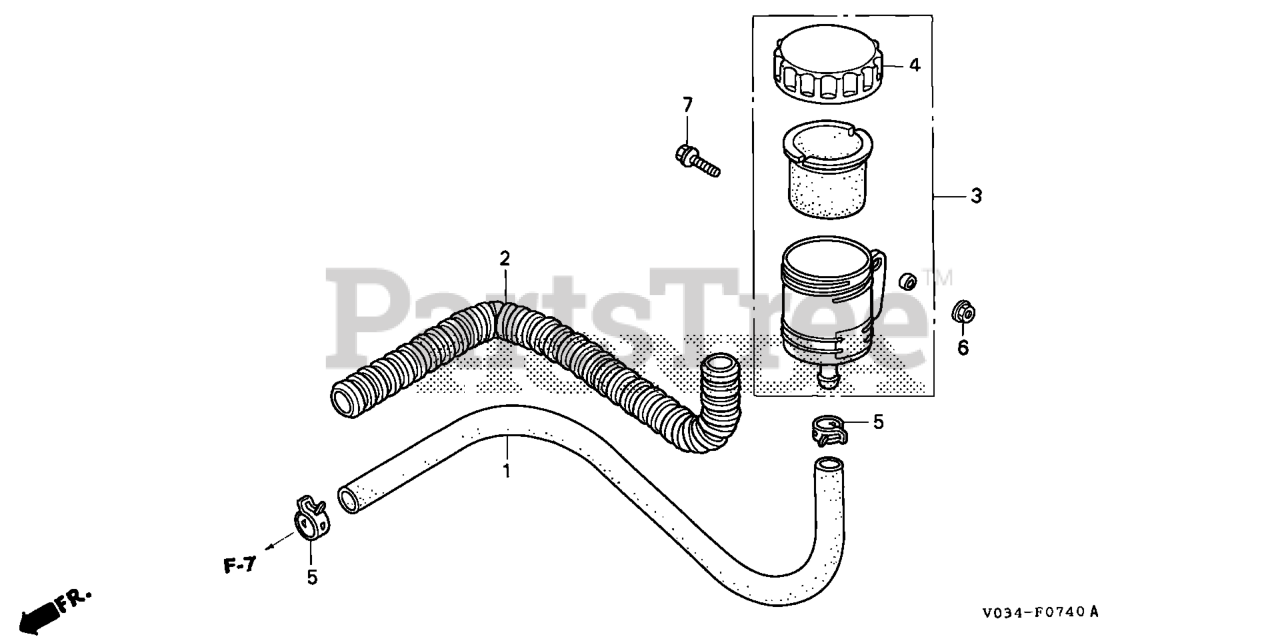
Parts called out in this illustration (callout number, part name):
2	PROTECTOR, OIL TUBE
3	TANK ASSY., OIL
4	FRAME, OIL CAP
5	CLAMP D (19MM)
6	NUT, FLANGE (6MM)
7	BOLT, FLANGE (6X16) Use from Engine SN 2056820.
